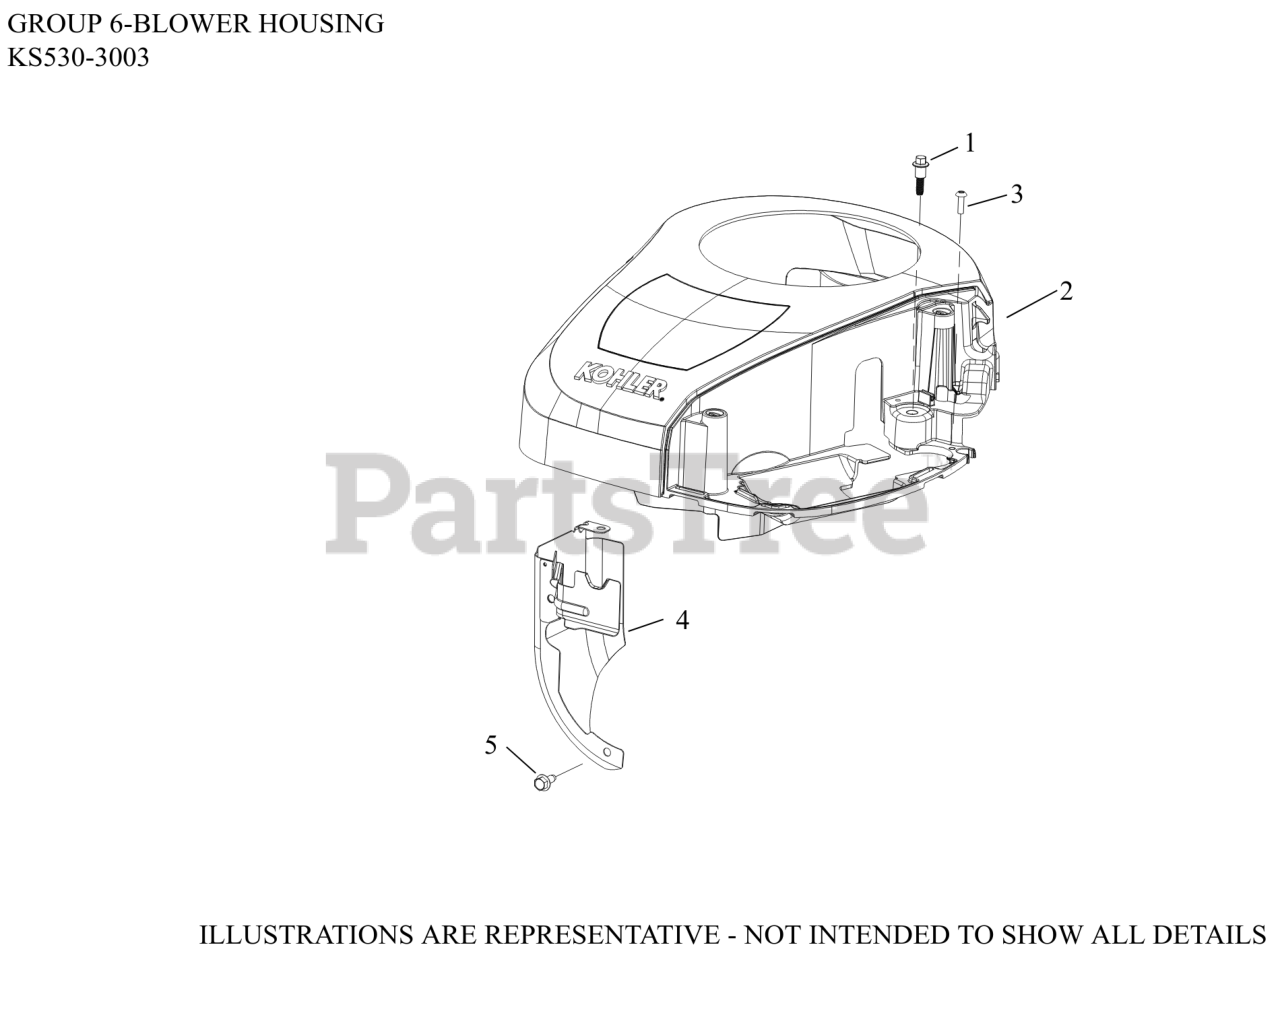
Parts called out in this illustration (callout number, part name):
1	SCREW, SHD THD FRM M6X1X26
2	KIT, BLOWER HOUSING
3	SCREW, HI-LOW
4	BAFFLE, BARREL ASSY
5	SCREW, THREAD FORMING
